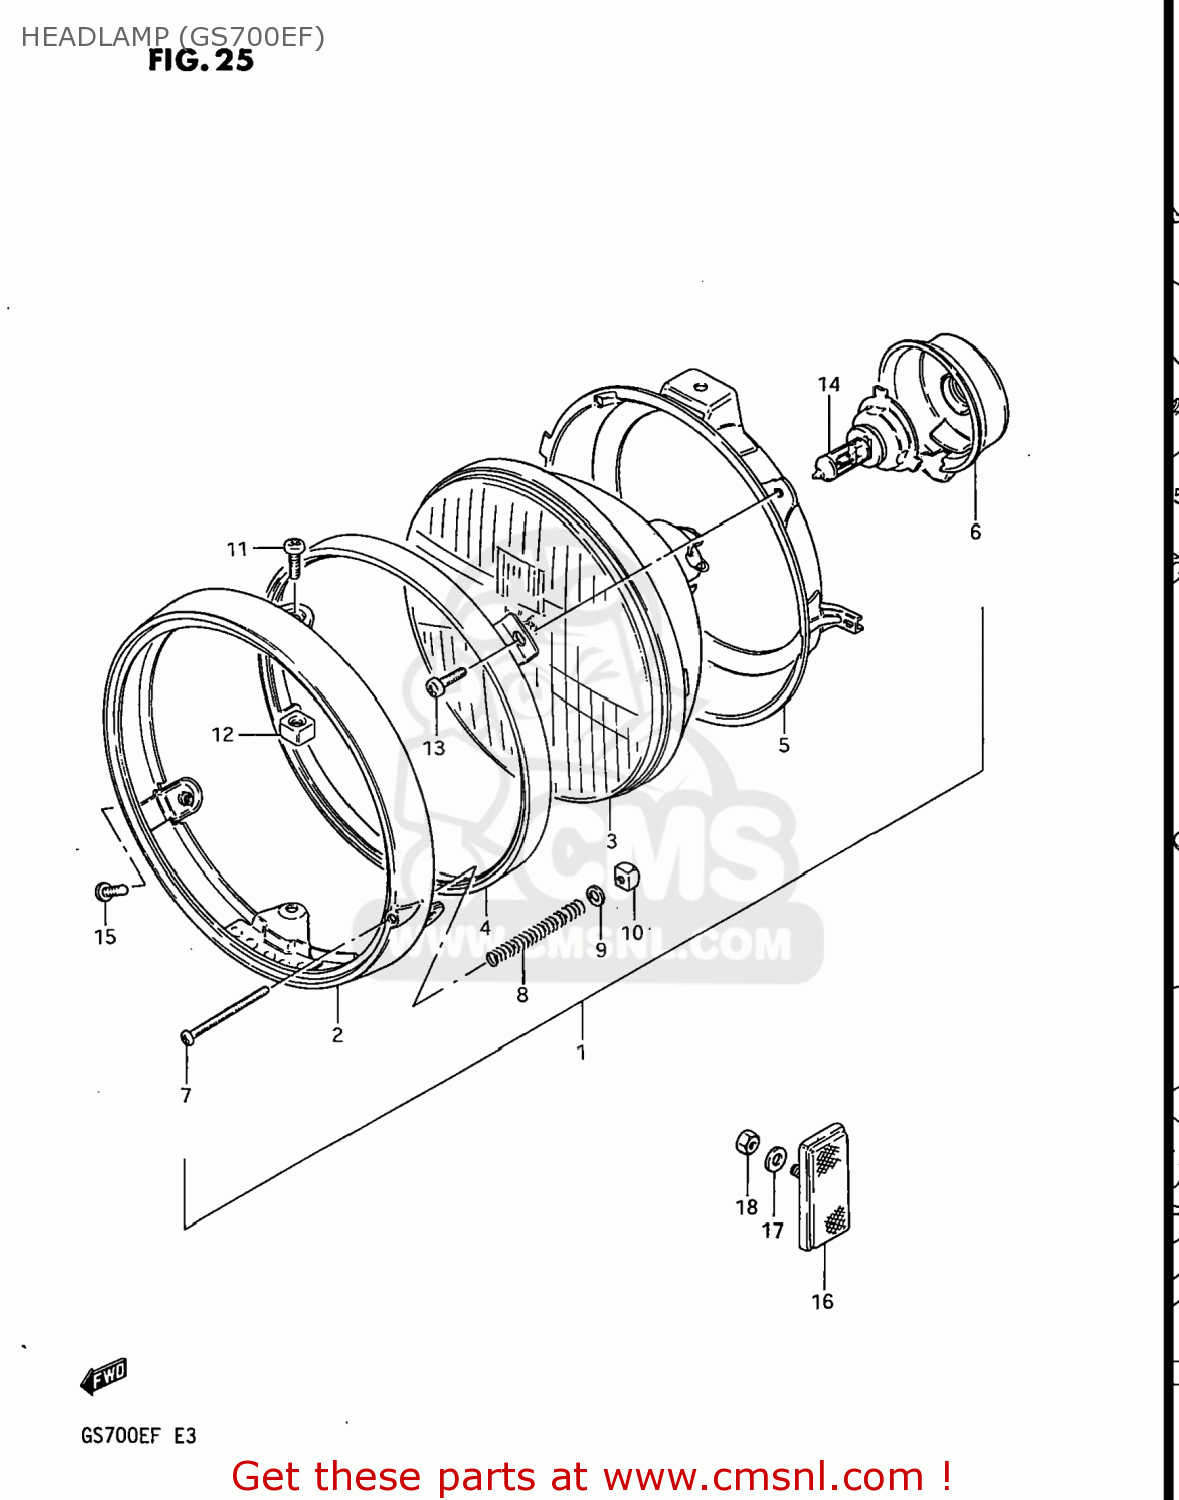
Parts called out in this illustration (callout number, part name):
1	HEADLAMP ASSEMBLY
2	RIM
3	LAMP UNIT
4	RETAINER
5	RING,MOUNTING
6	COVER,HEADLAMP SOCKET
7	SCREW
8	SPRING,HEADLAMP ADJUST
9	WASHER
10	NUT
11	SCREW
12	NUT
13	SCREW
14	BULB(12V60/55W,H4)
15	SCREW(5X12)
16	REFLEX REFLECTOR,FR SIDE
17	WASHER,5MM
18	NUT ,5MM
